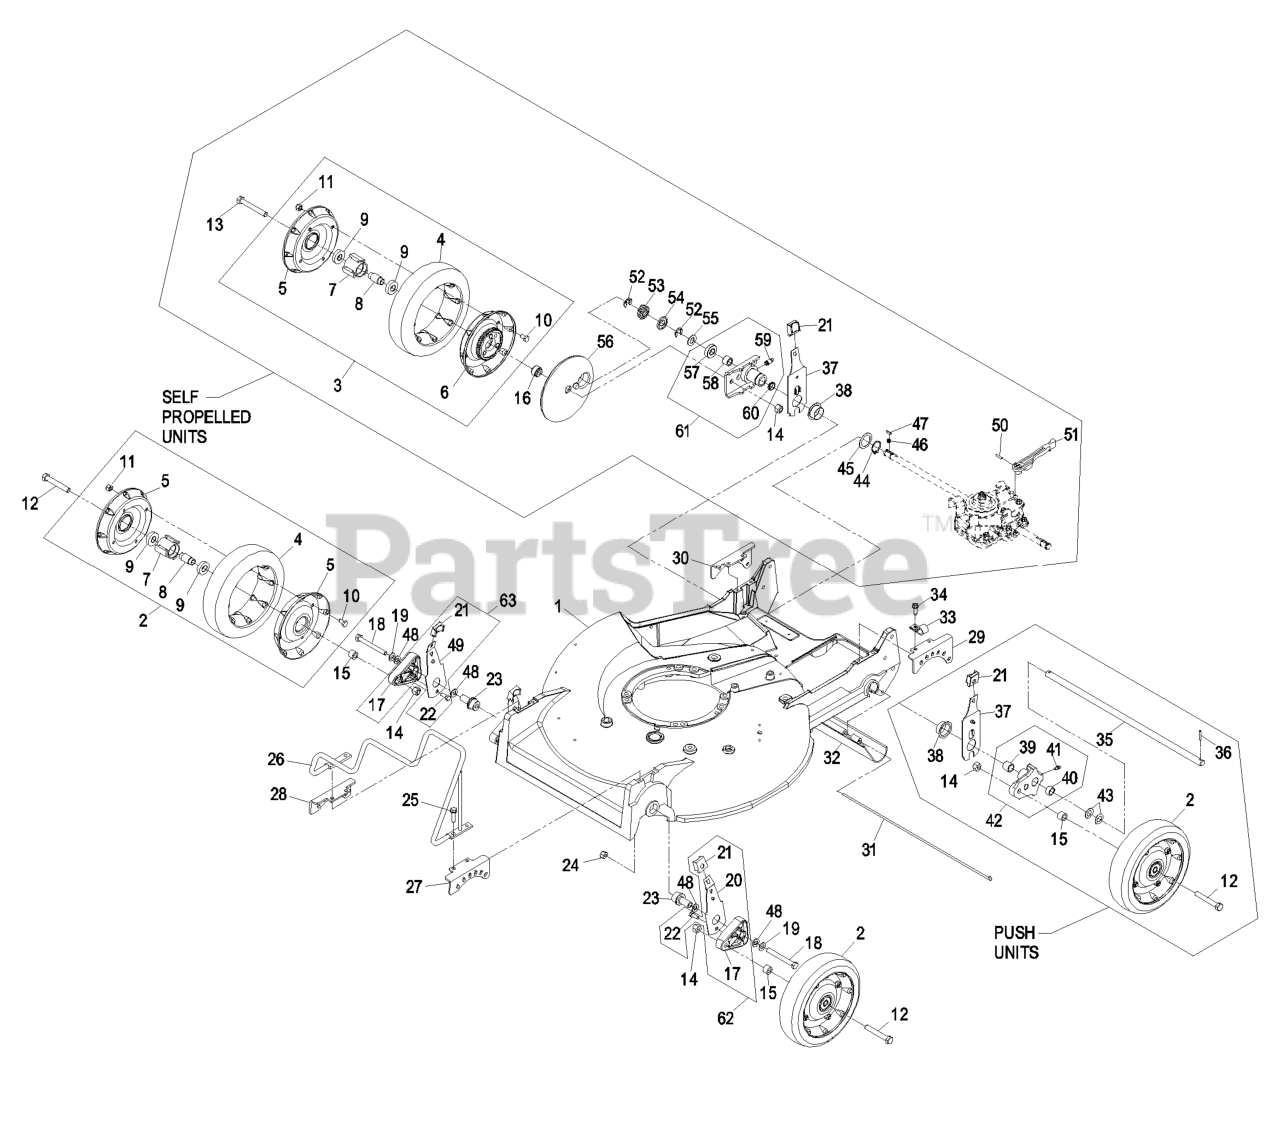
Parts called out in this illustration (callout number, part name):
7	HUB-BEARING
8	SPACER-BEARING
9	BEARING-WHEEL
10	SCREW-HH
11	NUT-LOCK, NI
12	BOLT-CARR
13	SCREW-HH
14	NUT-LOCK, CONE
15	SPACER-WHEEL
16	SPACER-COVER, WHEEL
17	ARM-PIVOT, FRONT
18	SCREW-HH
19	WASHER-FLAT
20	LH FRONT SPRING ARM ASM
21	KNOB-ARM
22	SCREW-HWHTF
23	BUSHING-PIVOT, WHEEL
24	NUT-LOCK, NI
25	SCREW-HWHTF
26	GUARD-ENGINE
27	BRACKET,QUADRANT FRONT LH
28	BRACKET,QUADRANT FRONT RH
29	BRACKET,QUADRANT REAR LH
30	BRACKET,QUADRANT REAR RH
31	ROD-SHIELD
32	SHIELD-TRAILING
33	CLIP-LOOM
34	SCREW-HWHTF
35	SHAFT-AXLE, REAR
36	PIN-SPIROL
37	REAR SPRING ARM ASM
38	CAP-END
39	BUSHING
40	BUSHING
41	FITTING-GREASE
42	PIVOT ARM ASM
43	WASHER-PLAIN
44	RING-RETAINING
45	WASHER
46	SPRING-COMPRESSION
47	KEY
48	WASHER-THRUST, NYLON
50	PIN-SPRING
51	LEVER-SHIFT
52	RING-RETAINING
53	GEAR-PINION
54	WASHER-THRUST, OUTER
55	WASHER-THRUST, OUTER
56	COVER-WHEEL
57	BEARING-WHEEL
59	ZERK
60	SEAL-OIL
61	PIVOT ARM ASM
62	ASM, ARM FRNT WHL LH
63	ASM, ARM FRNT WHL RH
